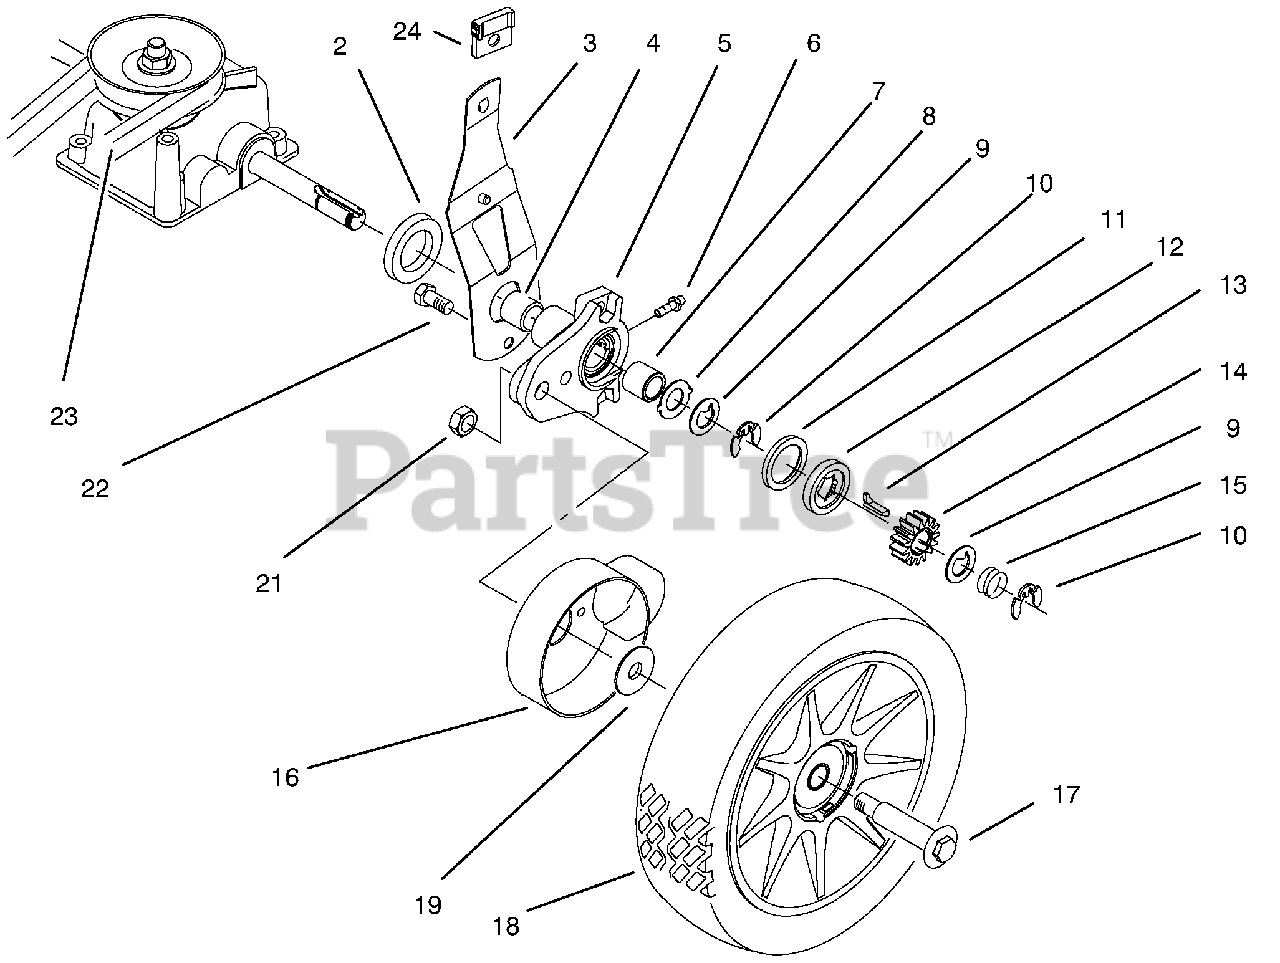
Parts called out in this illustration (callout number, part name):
2	Spacer-Axle Shaft
3	Spring Arm Ass'y
5	Pivot Arm Ass'y-Rear
6	Fitting-Grease (Ref.)
8	Washer-Thrust Pivot Arm
9	Washer-Thrust, Keyed
10	Ring-Klip
11	Ring-Friction
12	Washer-Clutch, Plastic
13	Key-Rocking LH
14	Gear-Pinion
15	Spring-Compression
16	Cover Wheel
17	Bolt-Wheel
18	Wheel Ass'y-8"
19	Washer-Stepped
